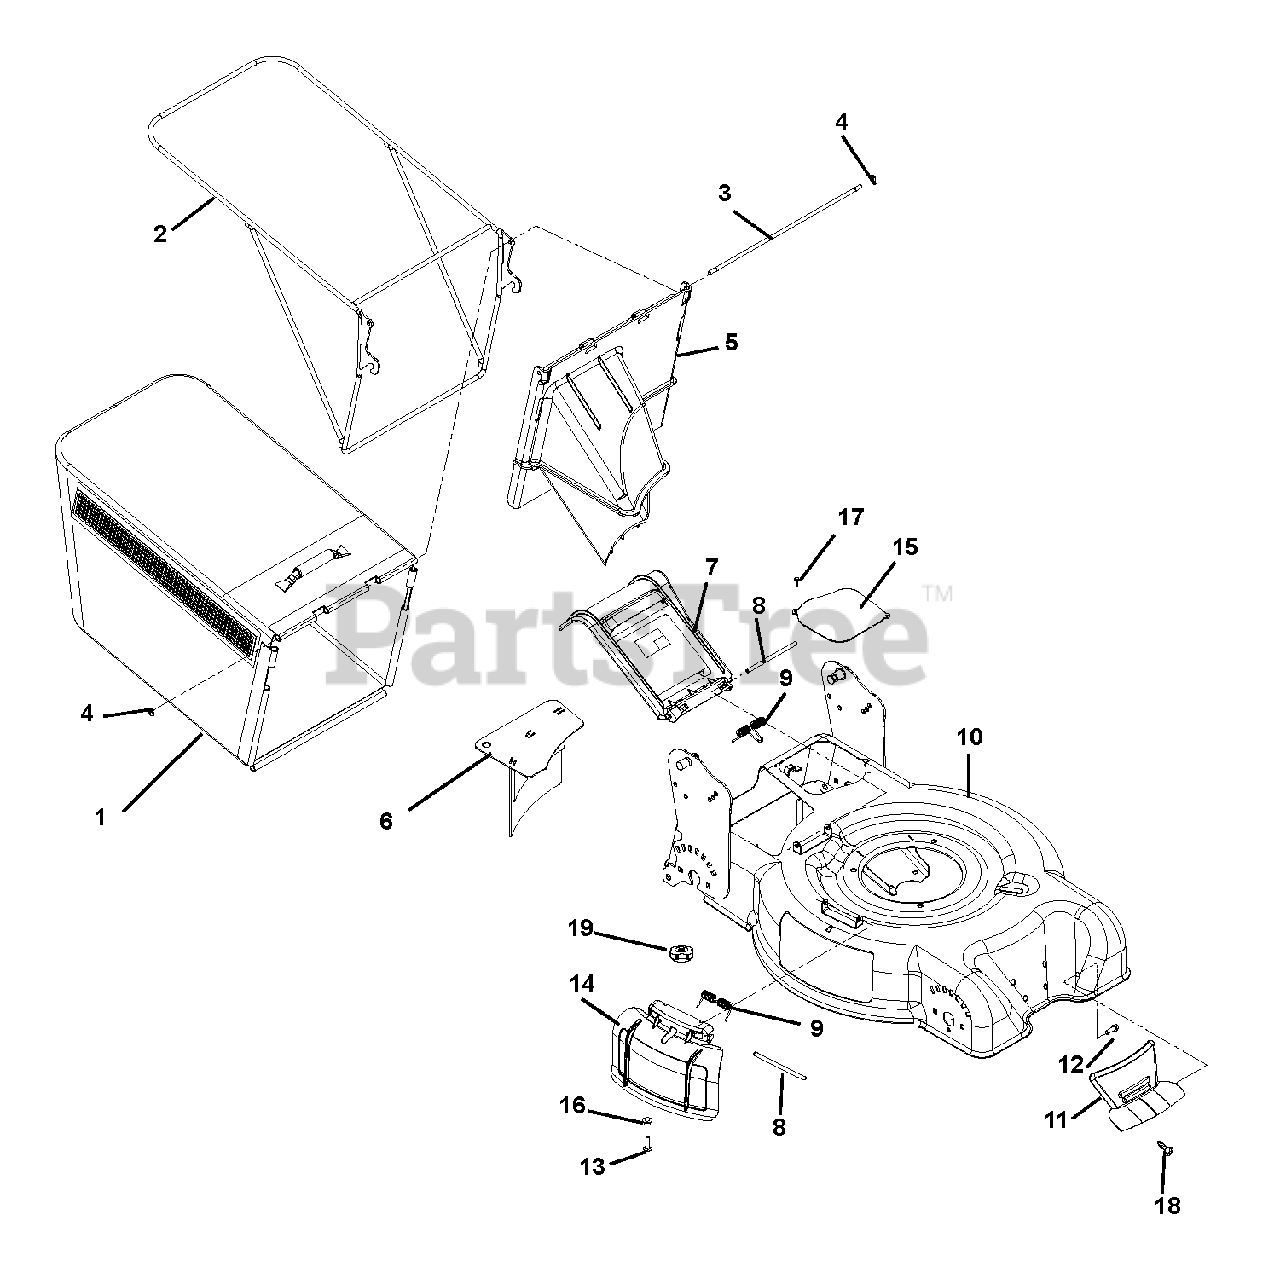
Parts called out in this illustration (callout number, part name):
1	Bagger, Gravely WBLM (911222, 3, 4)
2	Frame, Bagger (911222, 223, 224)
3	Rod, Hinge (911222, 223, 224)
4	Nut, Push .25 x .50 O.D. (911222, 223, 224)
5	Bagger Door (911222, 3, 4)
6	Mulch Plug
7	Rear Discharge Cover
8	Pin, Hinge
9	Spring, Torsion
10	21" Deck Weldment
11	Grill Insert
12	Screw, Tapping 12-12 x .75
13	Bolt, Round Head Square Neck .25-20 x .75
14	Mulch Cover
15	Cover, Transmission Access
17	Screw, Tapping 10-24 x .375 Hex Washer Head Thread Rolling (911220, 221, 222, 223
18	Screw, Self Drill/Tap
19	Knob, Clamping, .250-20 Nyloc
